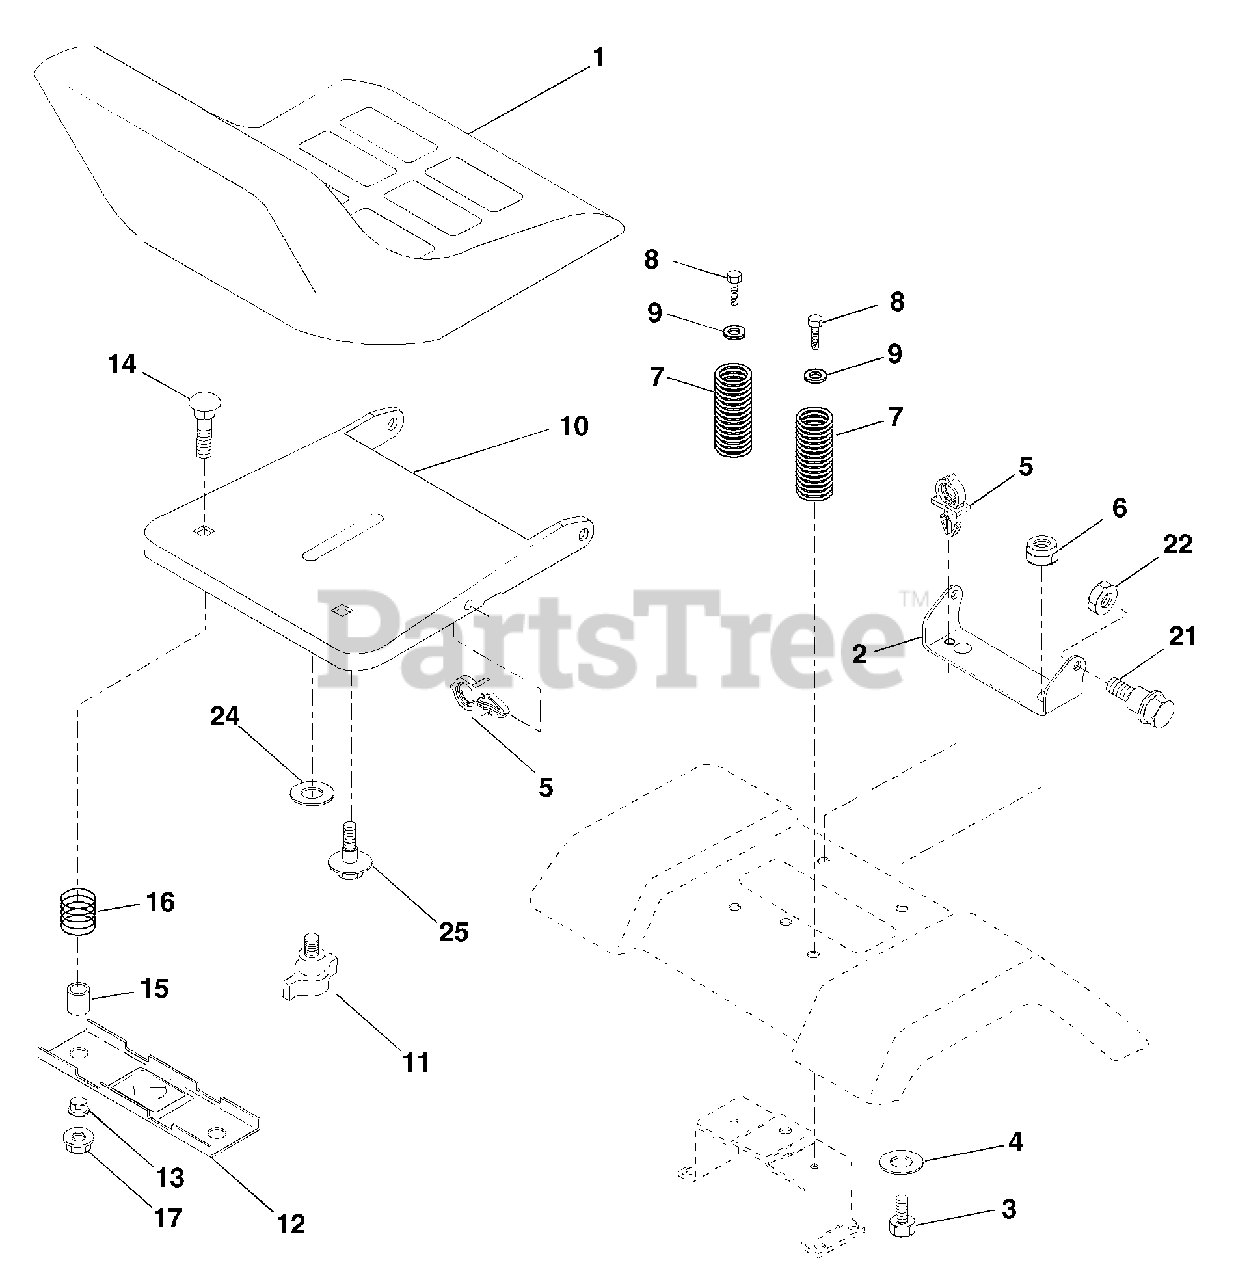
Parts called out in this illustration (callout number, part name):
1	Seat
2	Bracket Pivot Seat 8 720
3	Bolt Fin Hex 3/8-16 Unc X 1
4	Washer 13/32 X 1 X 10 Ga
5	Clip Push-In
6	Nut Hex w/Ins. 3/8-16 Unc
7	Spring Seat Cprsn 2 250 Blk Zi
8	Screw 3/8-16 X 1.5
9	Washer 13/32 X 1 X 14 Ga.
10	Pan Seat
11	Knob Seat
12	Bracket Mounting Switch
13	Bushing Snap Blk Nyl 50 Id
14	Bolt Rdhd Sqnk 1/4-20x1-1/2
15	Spacer Split 28x 88
16	Spring Cprsn
17	Nut Lock 1/4 Lge Flg Gr 5 Zinc
21	Bolt Shoulder 5/16-18 Unc
22	Nut Hex Lock W/Ins 5/16-18
24	Washer 17/32 X 1-3/16 X 12 Ga.
25	Bolt Shoulder 5/16-18 X 62
